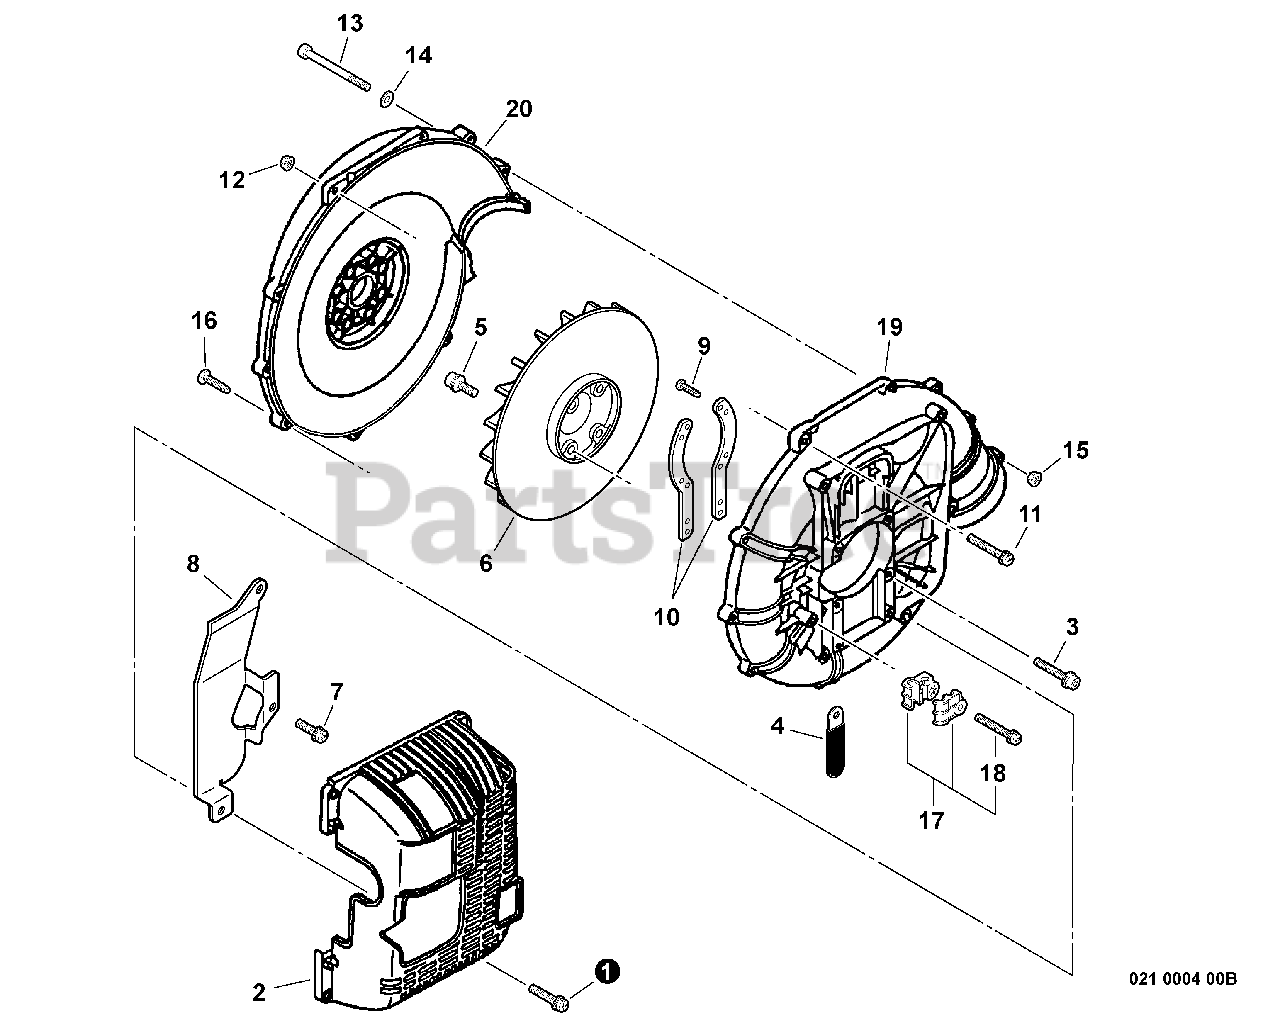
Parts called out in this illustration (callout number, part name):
1	SCREW 5×18
2	COVER, ENGINE
3	SCREW 5×32
5	BOLT 5×20
7	SCREW 5×10
8	INSULATOR
9	SCREW TAPPING 3×12
10	BRACKET, ENGINE
11	SCREW 5×40
12	NUT, FLANGE M5
13	BOLT 5×60
14	WASHER, FLAT 5.5×10×0.8
15	NUT, FLANGE M5
16	SCREW 5×30
17	CABLE HOLDER KIT
18	SCREW 5×25
19	COVER, FAN - OUTER
20	COVER, FAN - INNER
